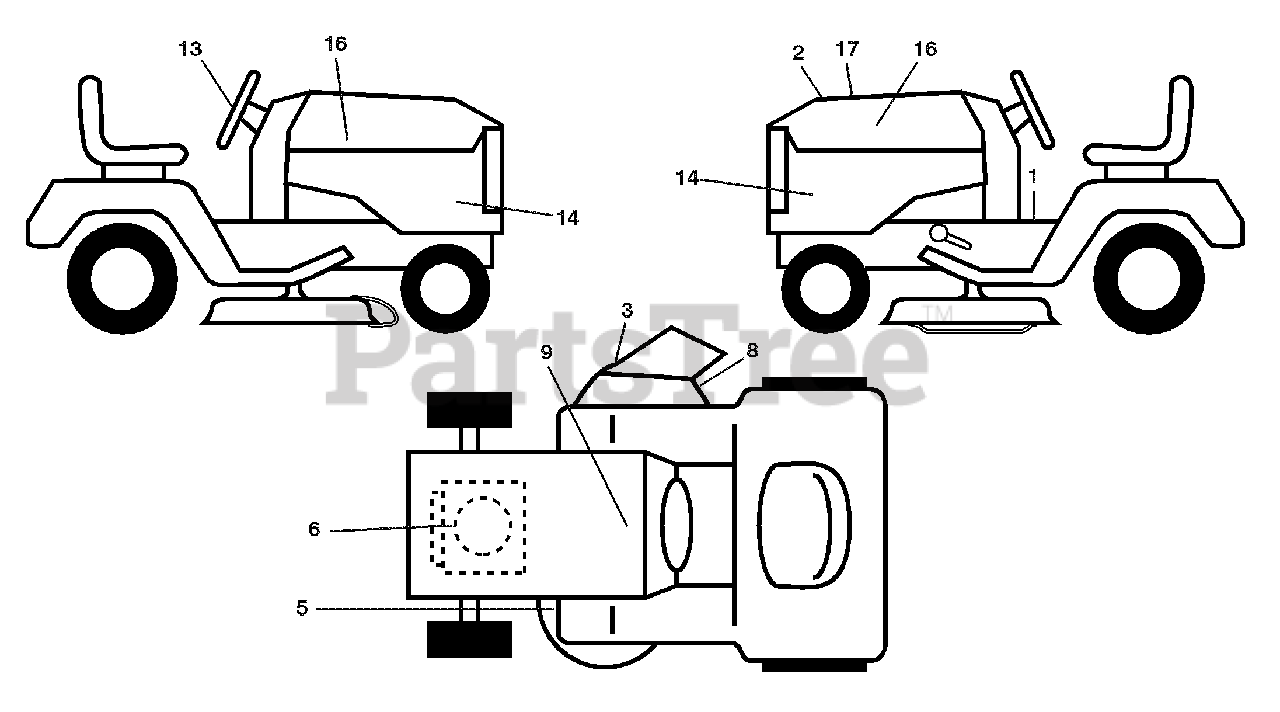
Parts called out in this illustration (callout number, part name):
1	Decal, Operator's
2	Decal, Hood Insert
3	Decal, Warning
5	Decal, Caution
6	Decal, Eng. HP
8	Decal, Mower Sch.
9	Decal, Battery Dnge/Poi
13	Decal, Steering Whl
14	Decal, Panel Side
16	Decal, Hood Logo
17	Decal, Replacement
17	Decal, Bypass
17	Pad, Footrest, LH
17	Pad, Footrest, RH
17	Manual, Owner's
